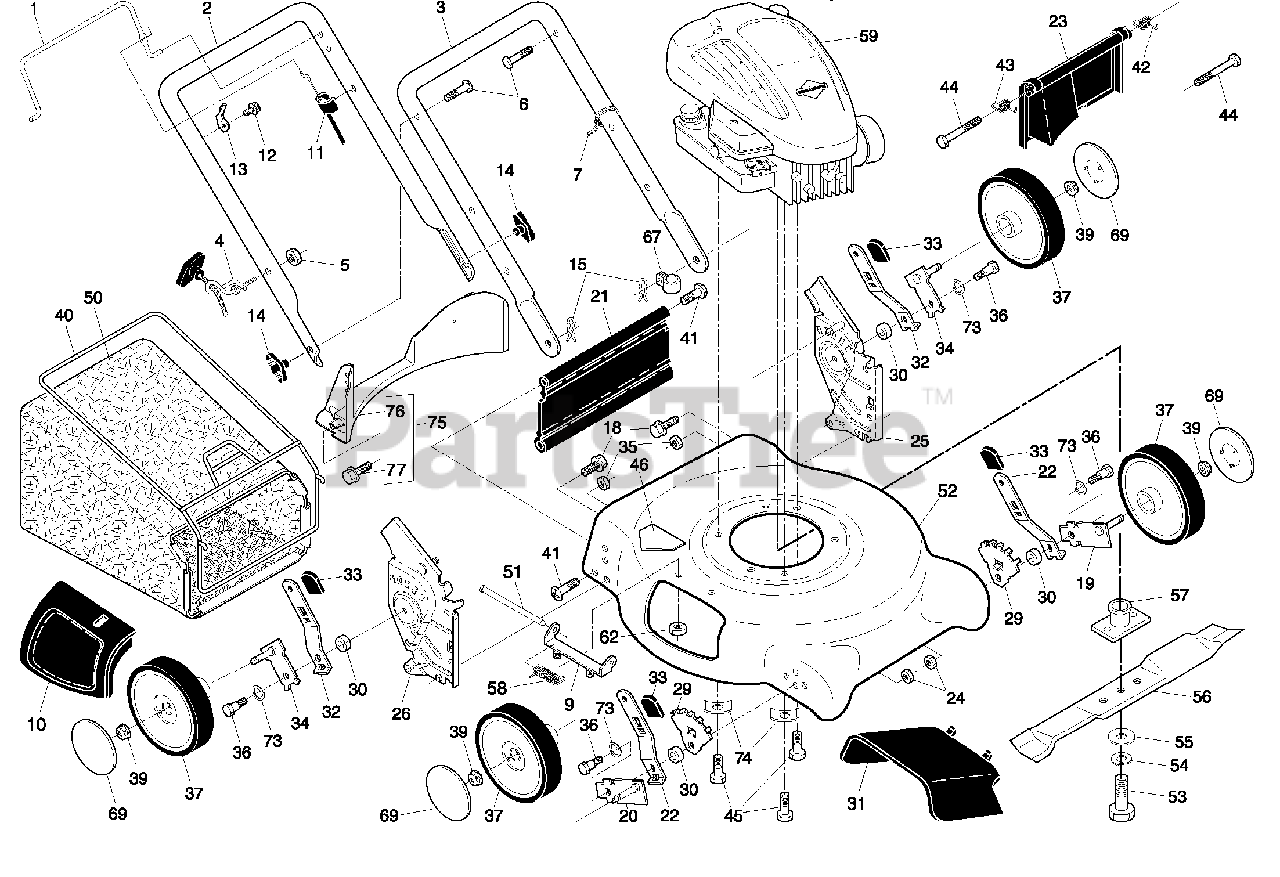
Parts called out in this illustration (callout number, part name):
1	Control Bar
2	Upper Handle
3	Lower Handle
4	Rope Guide
6	Handle Bolt
7	Wire Tie
9	Hinge Bracket Assembly
10	Mulcher Door
11	Engine Zone Control Cable
12	Hex Washer Head Screw
13	Up-Stop Bracket
14	Handle Knob
15	Hairpin Cotter
18	Screw 1/4-20 x 3/8
19	Axle Arm Assembly, Front, LH
20	Axle Arm Assembly, Front, RH
21	Rear Skirt
22	Selector Spring, Front
23	Rear Door Assembly
24	Locknut, Hex
25	Handle Bracket, LH
26	Handle Bracket, RH
28	Spring, Torsion
29	Wheel Adjusting Bracket
30	Spacer
31	Discharge Deflector
32	Selector Spring, Rear
33	Selector Knob
34	Axle Arm Assembly, Rear
35	Nut, Hex
36	Shoulder Bolt 5/16-18
37	Wheel & Tire Assembly
39	Locknut, Hex, Flanged
40	Frame, Grass Bag
41	Hinge Screw
42	Spring, Rear Door, LH
43	Spring, Rear Door, RH
44	Bolt, Rear Skirt
45	Screw, Hex Head, Threaded, Rolled 3/8-16 x 1
46	Danger Decal
50	Grass Bag
51	Hinge Rod
52	Kit, Housing Assembly
53	Screw, Hex Head, Grade 8 3/8-24 x 1-3/8
54	Helical Lockwasher
55	Hardened Washer
56	21" Blade
57	Blade Adapter
62	Nut, Hex, Nylock 1/4-20
67	Clip, Cable
69	Hubcap
73	Washer, Flat
74	Washer, Special, Engine
75	Kit, Rear Baffle
76	Baffle, Rear
77	Screw, Rear Baffle
77	Operator's Manual, English
77	Operator's Manual, French
77	Repair Parts Manual
